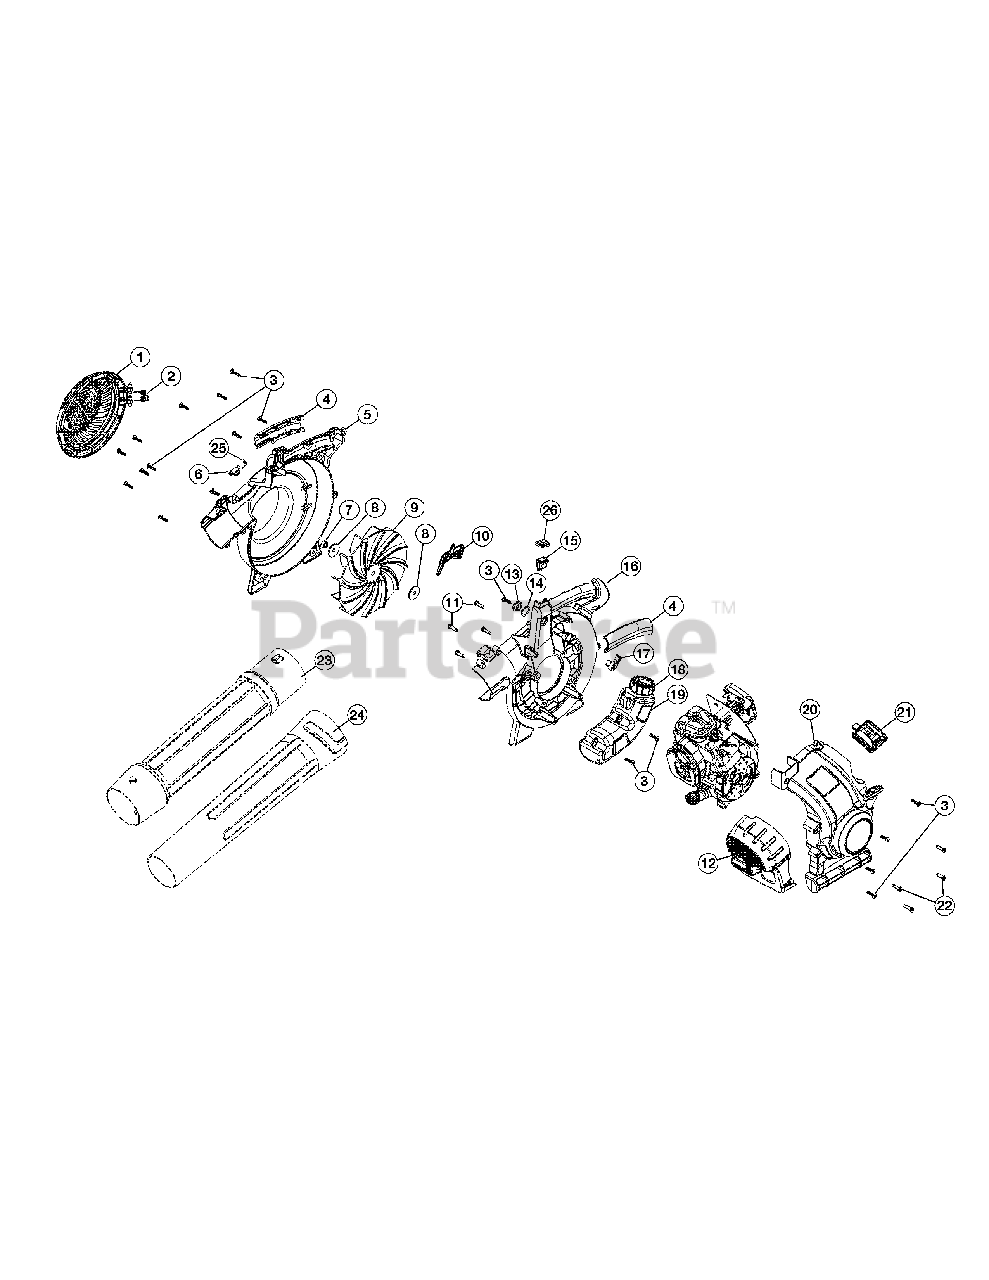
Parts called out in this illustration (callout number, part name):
1	Intake Cover
4	Handle Grips
5	Impeller Housing
6	Latch Tube
10	Throttle Trigger
11	Screw
12	Muffler Cover
13	Inner Trigger Lock
14	Wavey Washer
16	Impeller Housing
17	Outer Trigger Lock
19	Fuel Tank Assembly
20	Engine Cover Assembly
21	Spark Plug Cover
23	Upper Tube
24	Lower Tube
25	Latch Spring
26	Switch Cover
